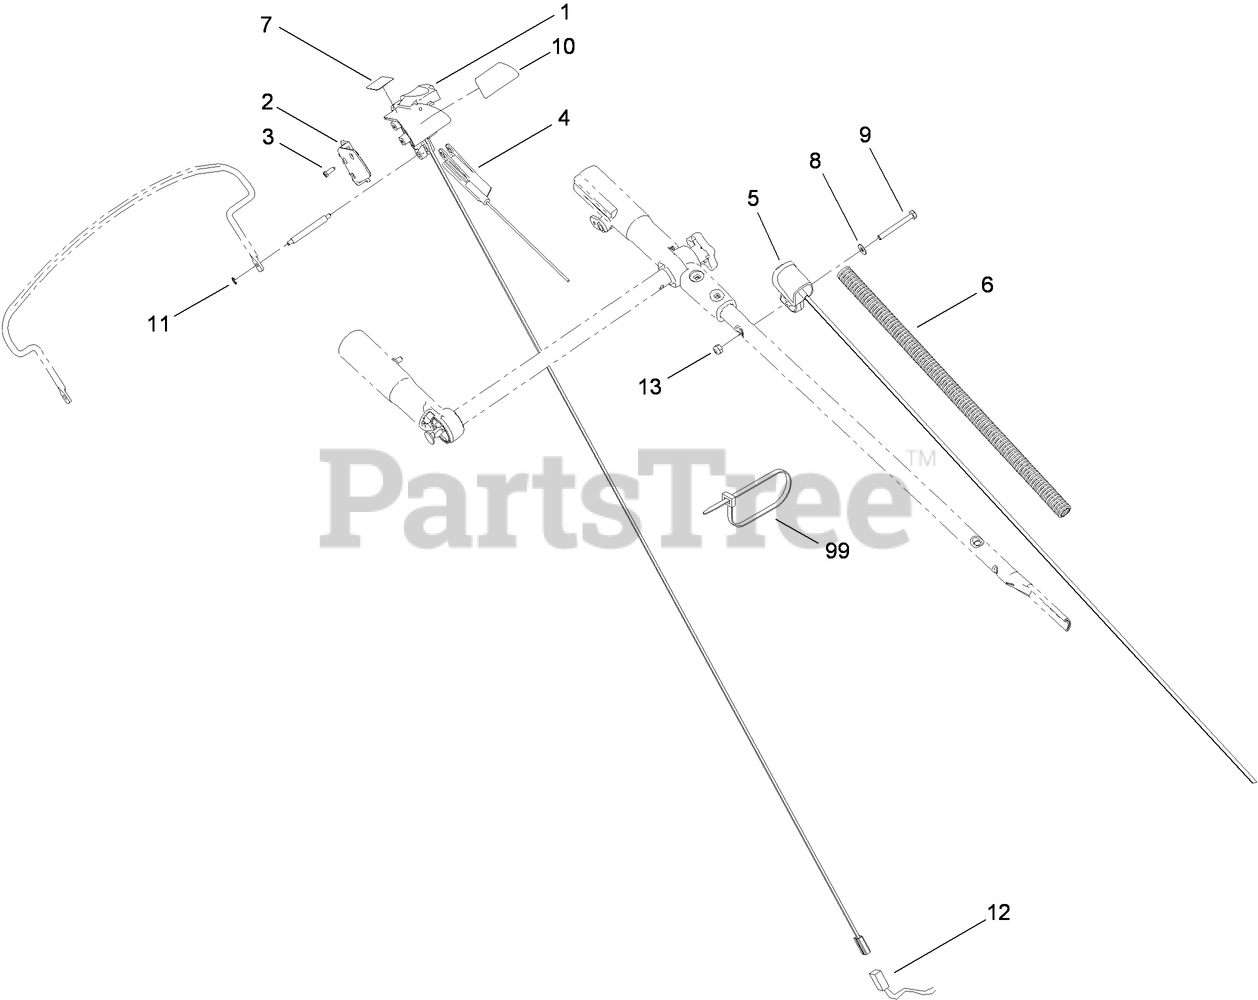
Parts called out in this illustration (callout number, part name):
1	SAFETY SWITCH ASM
2	COVER-SWITCH
3	SCREW-PPH
4	CABLE-BCS
5	SWITCH HOUSING ASM
6	TUBE-LOOM, SPLIT
7	DECAL-CONTROL, BLADE
8	WASHER-FLAT
9	SCREW-HH
10	DECAL-BRAKE CONTROL, BLADE
11	RING-RETAINING
12	HARNESS-WIRE
13	NUT-LOCK, NI
99	TIE-CABLE
